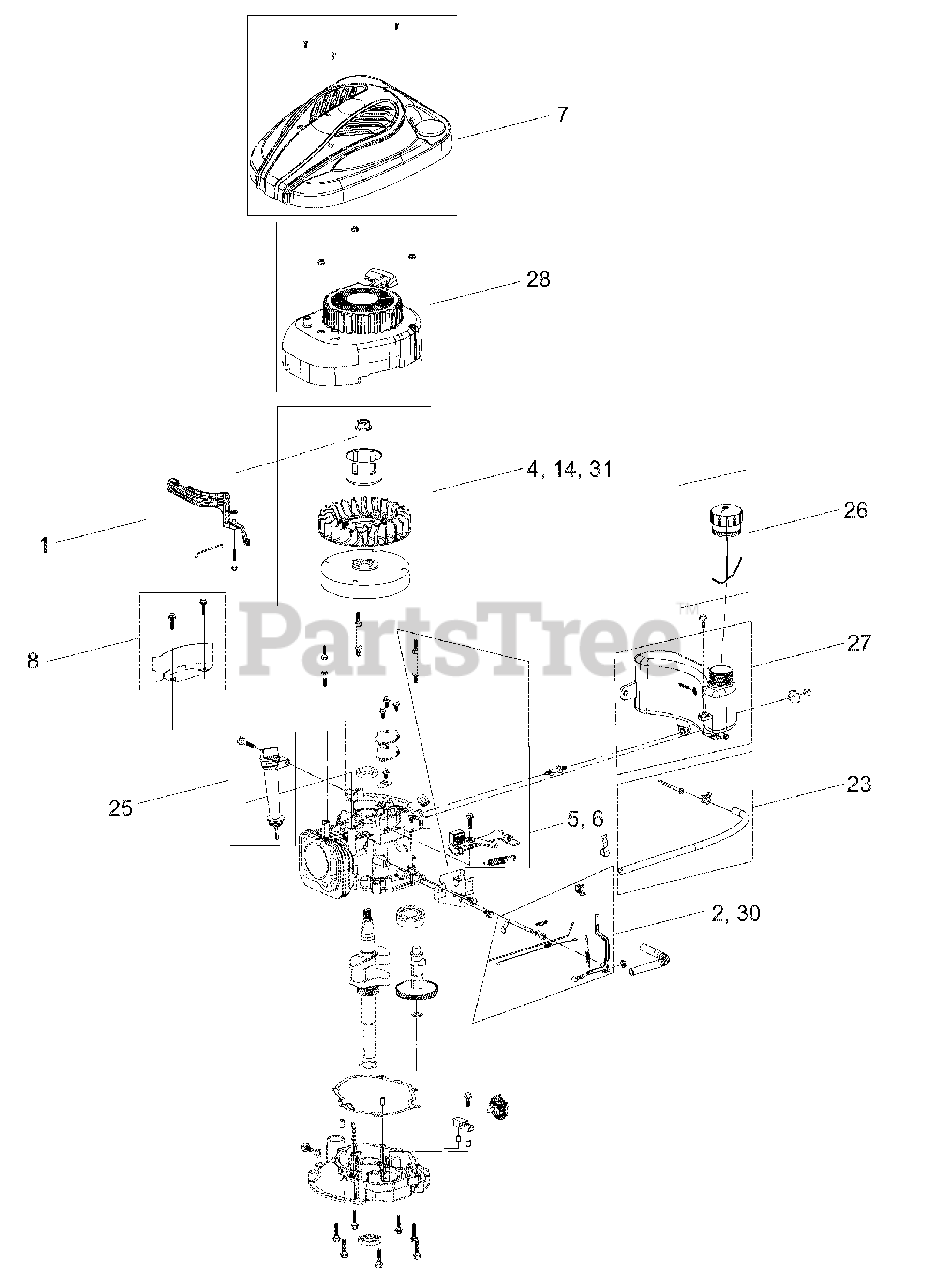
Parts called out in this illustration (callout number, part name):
1	KIT, AIR VANE CHOKE - SVC
2	KIT, GOVERNOR ARM - SVC
6	KIT, E-START BRAKE ASM - SVC
7	KIT, ARIENS STYLE - SVC
8	KIT, FLYWHEEL SHIELD - SVC
14	KIT, FLYWHEEL AND FAN - SVC
23	KIT, FUEL LINE W/FILTER - SVC
25	DIPSTICK, OIL - SVC
26	TUBE, OIL DIPSTICK - SVC
27	ASM, FUEL TANK W/HARDWARE
28	KIT, RECOIL - SVC
